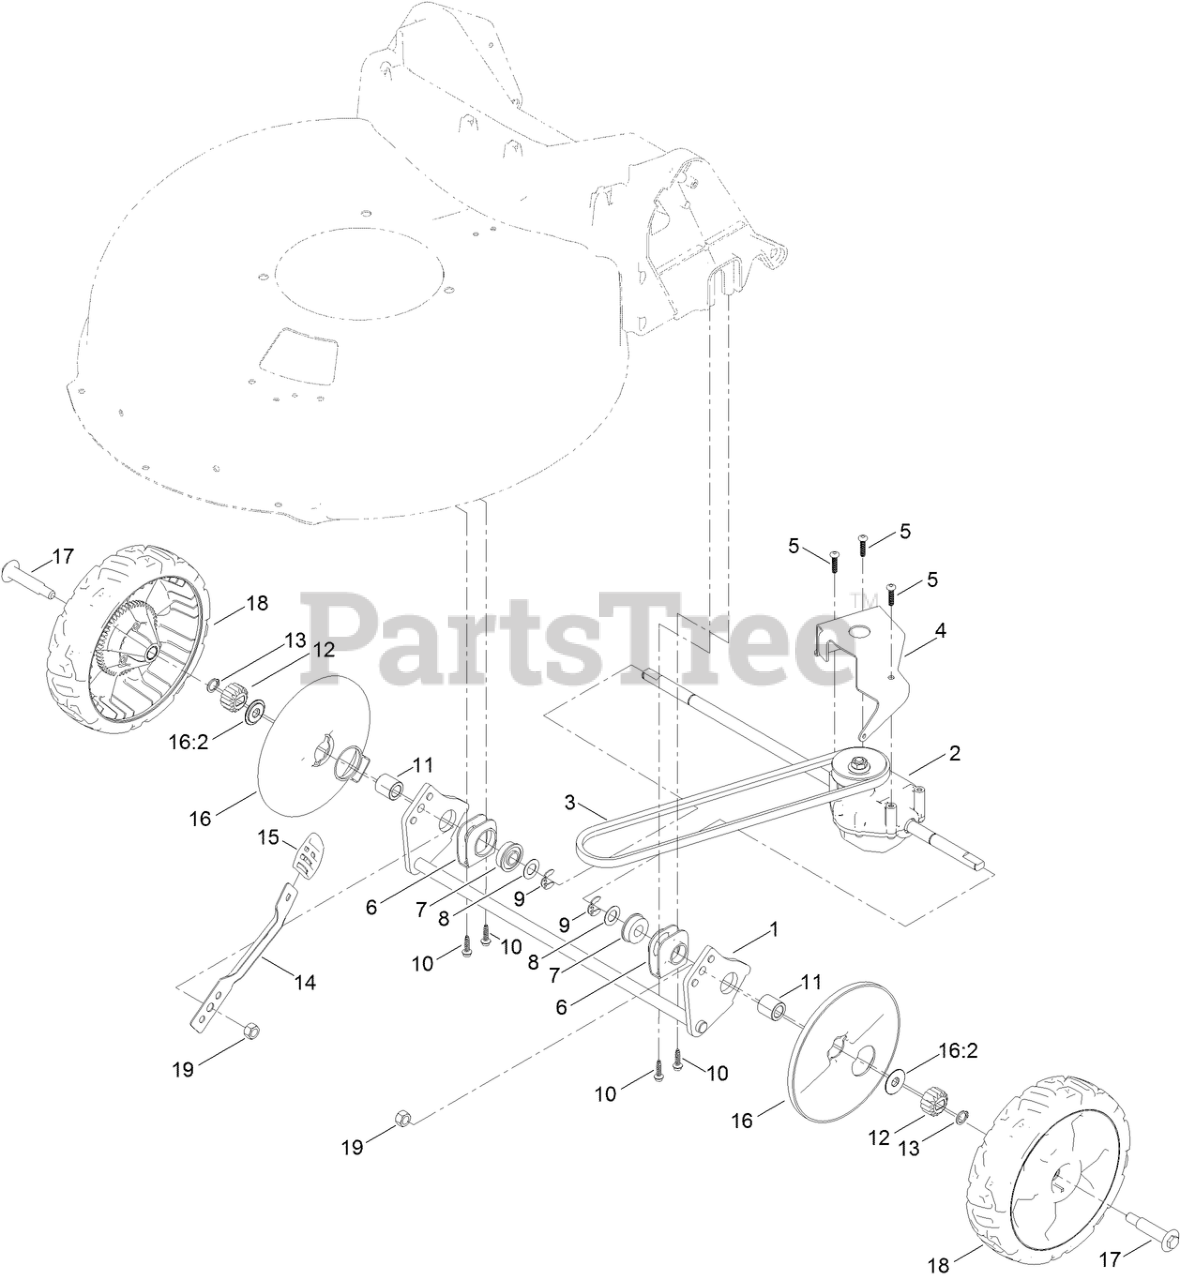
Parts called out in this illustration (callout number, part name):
2	TRANSMISSION
4	BRACKET-TRANSMISSION
5	SCREW-PLASTITE
6	RETAINER-BEARING
7	BEARING-BALL
8	WASHER-PLAIN
9	RING-RETAINING,CLIP
10	SCREW-HWH
11	BUSHING-SLEEVE
12	GEAR-PINION, 15T
13	RING-RETAINING
14	ARM-SPRING
15	KNOB-LEVER, HOC
16	WHEEL COVER ASM
16:2	WASHER-STEPPED
17	BOLT-SHOULDER
18	WHEEL GEAR ASM, 8IN
19	NUT-HEX
